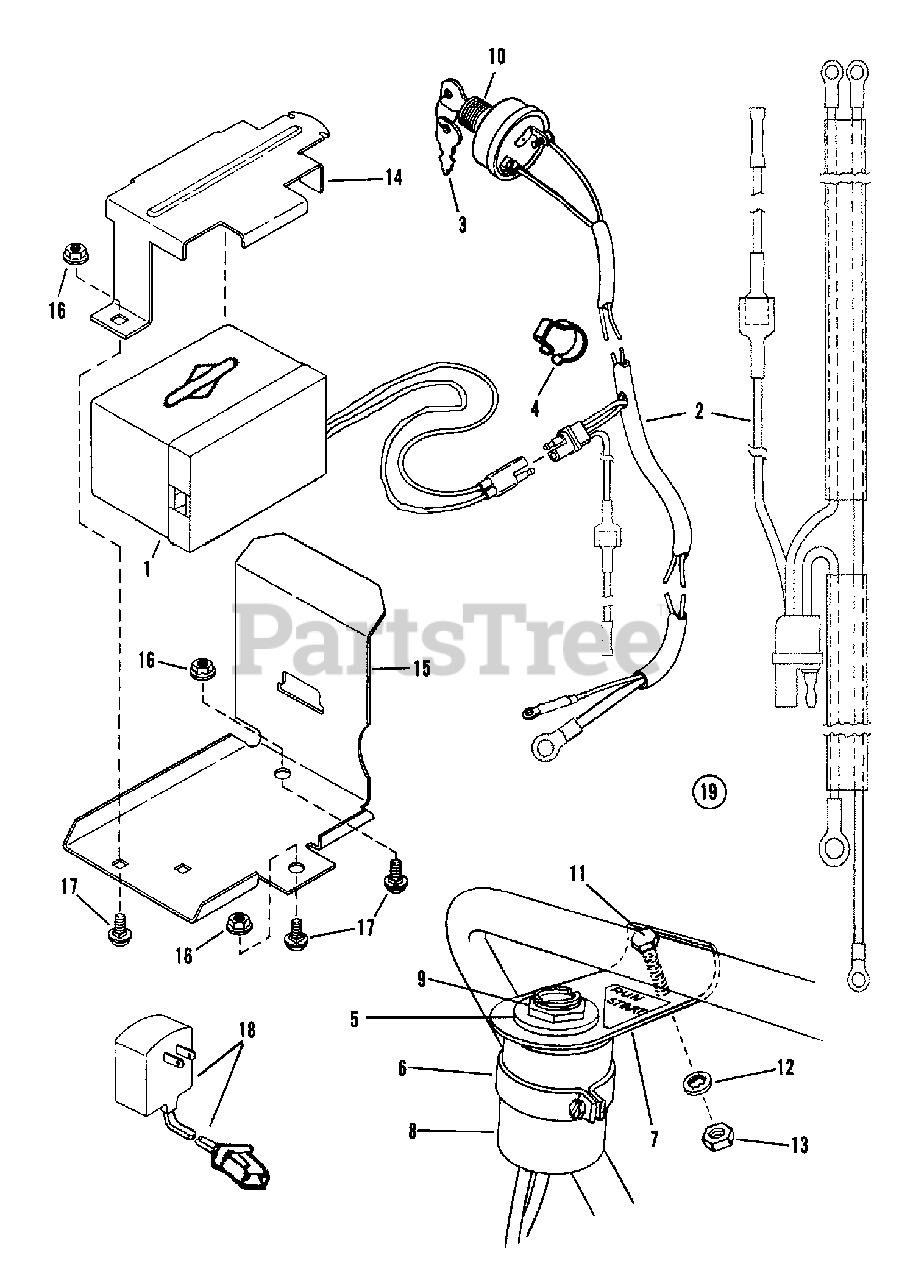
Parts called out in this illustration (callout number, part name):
2	HARNESS, Battery
3	KEY, (Set of 2)
4	CLIP, Wiring Harness
5	ITLW, 5/8 YZ
6	CLAMP
7	BRKT & DECAL, Ignition Switch
8	COVER, Switch
9	HN, 5/8-32 ZP
10	SWITCH, Ignition (Use B & S terminals only)
11	SCREW, 1/4-28 x 1 3/8 Hex Head Cap
12	WASHER, 1/4 Internal Tooth Lock
13	NUT, 1/4-28 Hex
14	COVER, Battery
15	BRACKET, Battery
16	NUT, 5/16-18 Hex Flange Lock
17	BOLT, 5/16-18 x 1/2" Carriage
